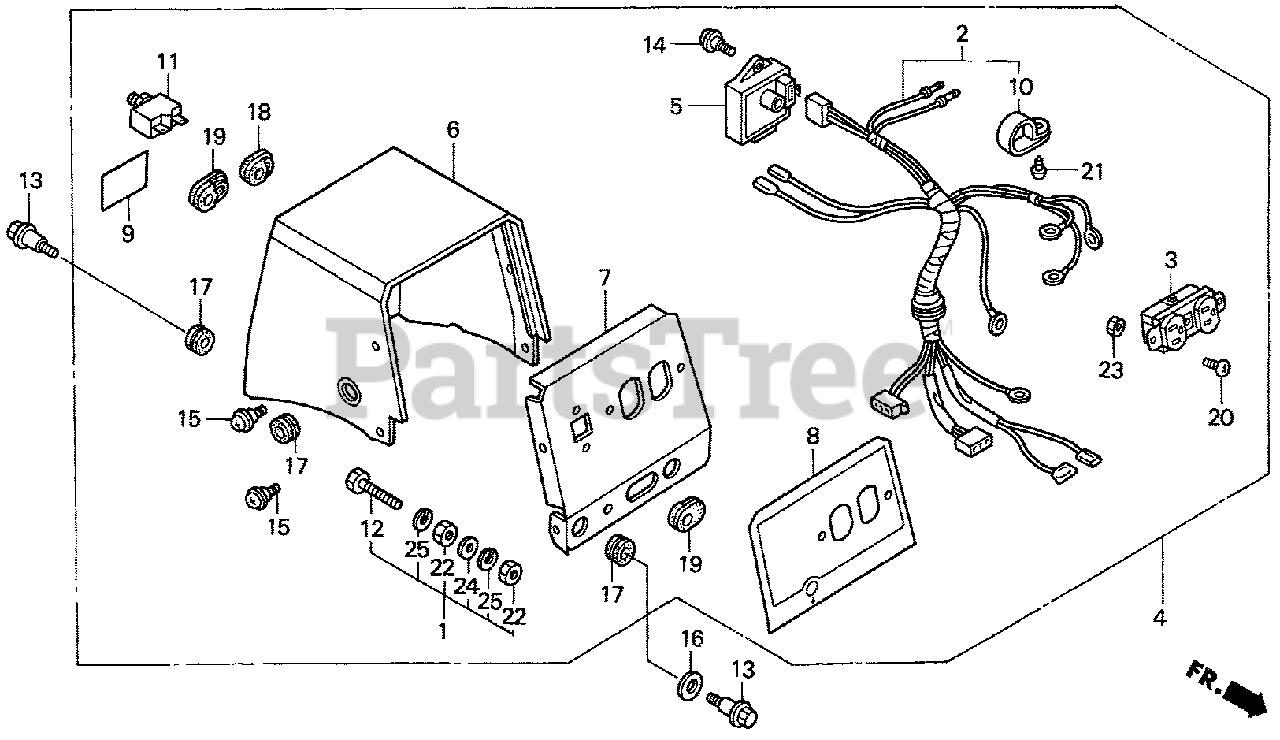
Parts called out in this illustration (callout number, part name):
1	TERMINAL SET, GROUND
2	WIRE HARNESS ASSY.
3	RECEPTACLE (125V-15A)
4	BOX ASSY., CONTROL (EZ-A)
5	REGULATOR UNIT, AUTOMATIC
6	COVER, CONTROL BOX
7	PANEL, FR.
8	MARK, SWITCH PANEL
9	MARK, PROTECTOR (ON/OFF)
10	TIE, CABLE
11	PROTECTOR, CIRCUIT (13A)
12	BOLT, HEX. (6X28)
13	BOLT, ADJUSTING (6X20)
14	SCREW, SPECIAL (5X12)
15	SCREW, SPECIAL (4X7.5)
16	WASHER, PLAIN (21MM)
17	RUBBER, CONTROL BOX
19	RUBBER, CONTROL BOX
20	SCREW, PAN (4X6)
21	SCREW, TAPPING (4X12)
22	NUT, HEX. (6MM)
24	WASHER, PLAIN (6MM)
25	WASHER, SPRING (6MM)
